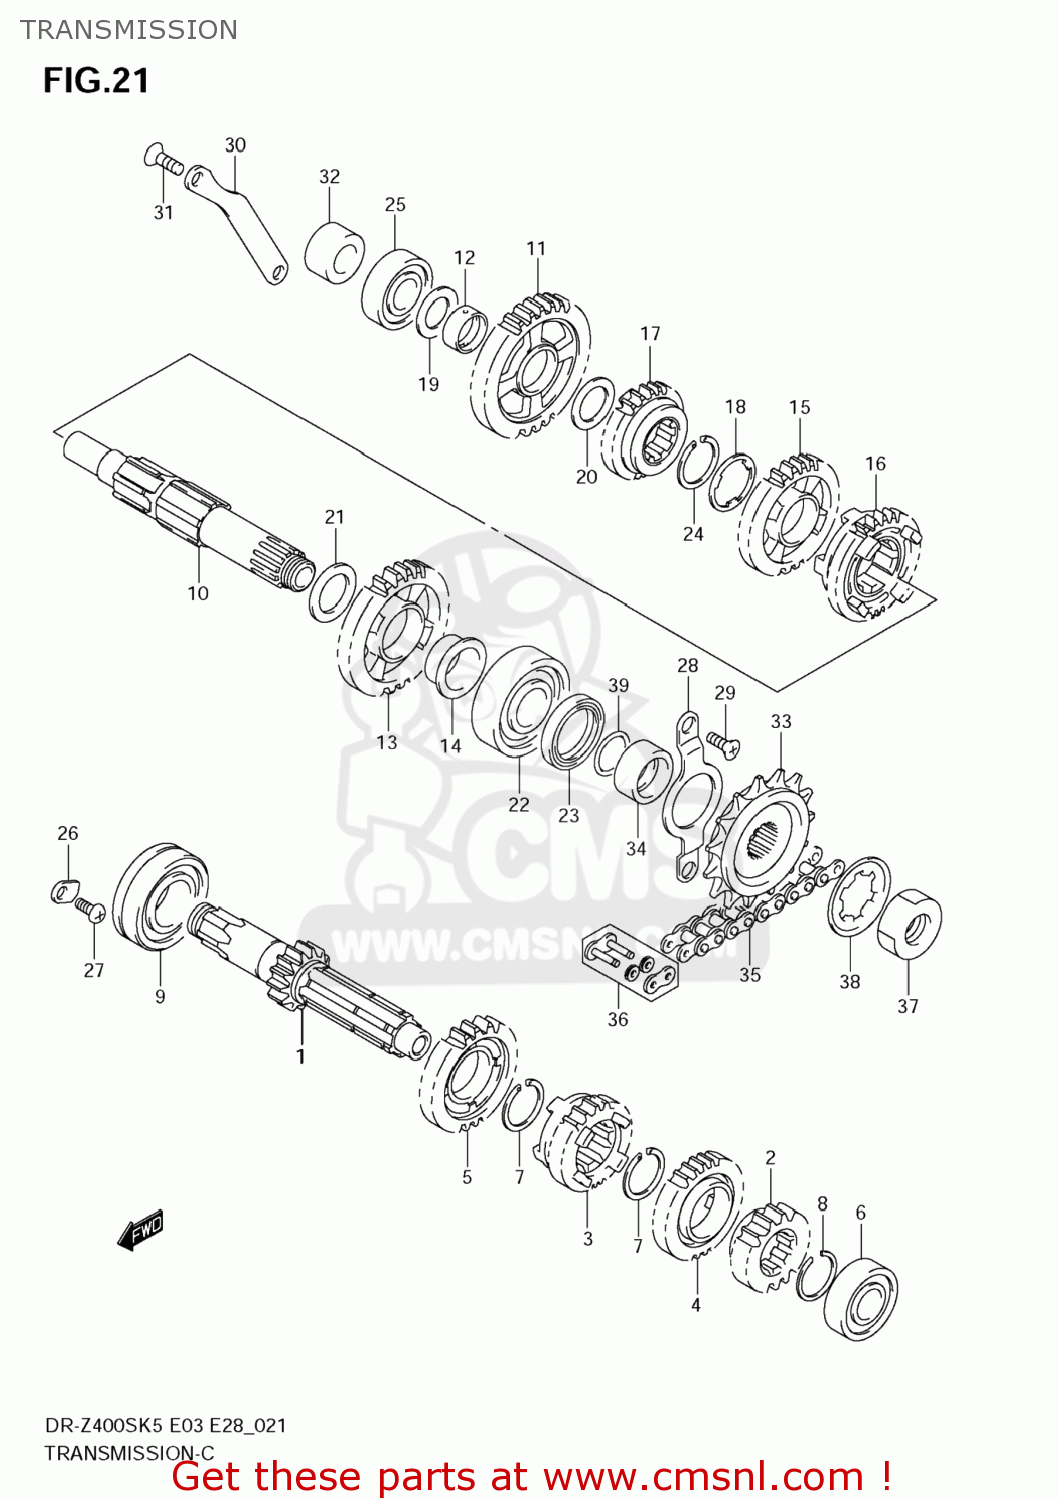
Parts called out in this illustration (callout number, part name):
1	SHAFT,COUNTER(NT:14)
2	GEAR,2ND DRIVE(NT:15)
3	GEAR,3RD DRIVE(NT:16)
4	GEAR,4TH DRIVE(NT:22)
5	GEAR,5TH DRIVE(NT:22)
6	BEARING(17X40X12)
7	CIRCLIP
8	CIRCLIP
9	BEARING(25X52X15)
10	SHAFT,DRIVE
11	GEAR,1ST DRIVEN(NT:32)
12	BUSH,1ST DRIVEN GEAR
13	GEAR,2ND DRIVEN(NT:26)
14	BUSH,2ND DRIVEN GEAR
15	GEAR,3RD DRIVEN(NT:22)
16	GEAR,4TH DRIVEN(NT:24)
17	GEAR,5TH DRIVEN(NT:19)
18	WASHER,LOCK
19	SHIM(17X30X1)
20	SHIM(20X30X1)
21	SHIM(22X34X1)
22	BEARING(22X56X16)
23	SEAL,OIL(30X40X6)
24	CIRCLIP
25	BEARING(17X40X12)
26	RETAINER
27	BOLT(6X12)
28	RETAINER,DRIVE SHAFT OIL SEAL
29	SCREW(6X14)
30	RETAINER,KICK IDLE GEAR
31	SCREW
32	SPACER(17X30.5X16.3)
33	SPROCKET,ENGINE(15T)
34	SPACER,ENGINE SPROCKET
35	CHAIN ASSEMBLY,DRIVE RK520
36	JOINT SET,CHAIN
37	NUT
38	WASHER,LOCK
39	O RING(D:2.5,ID:21)
